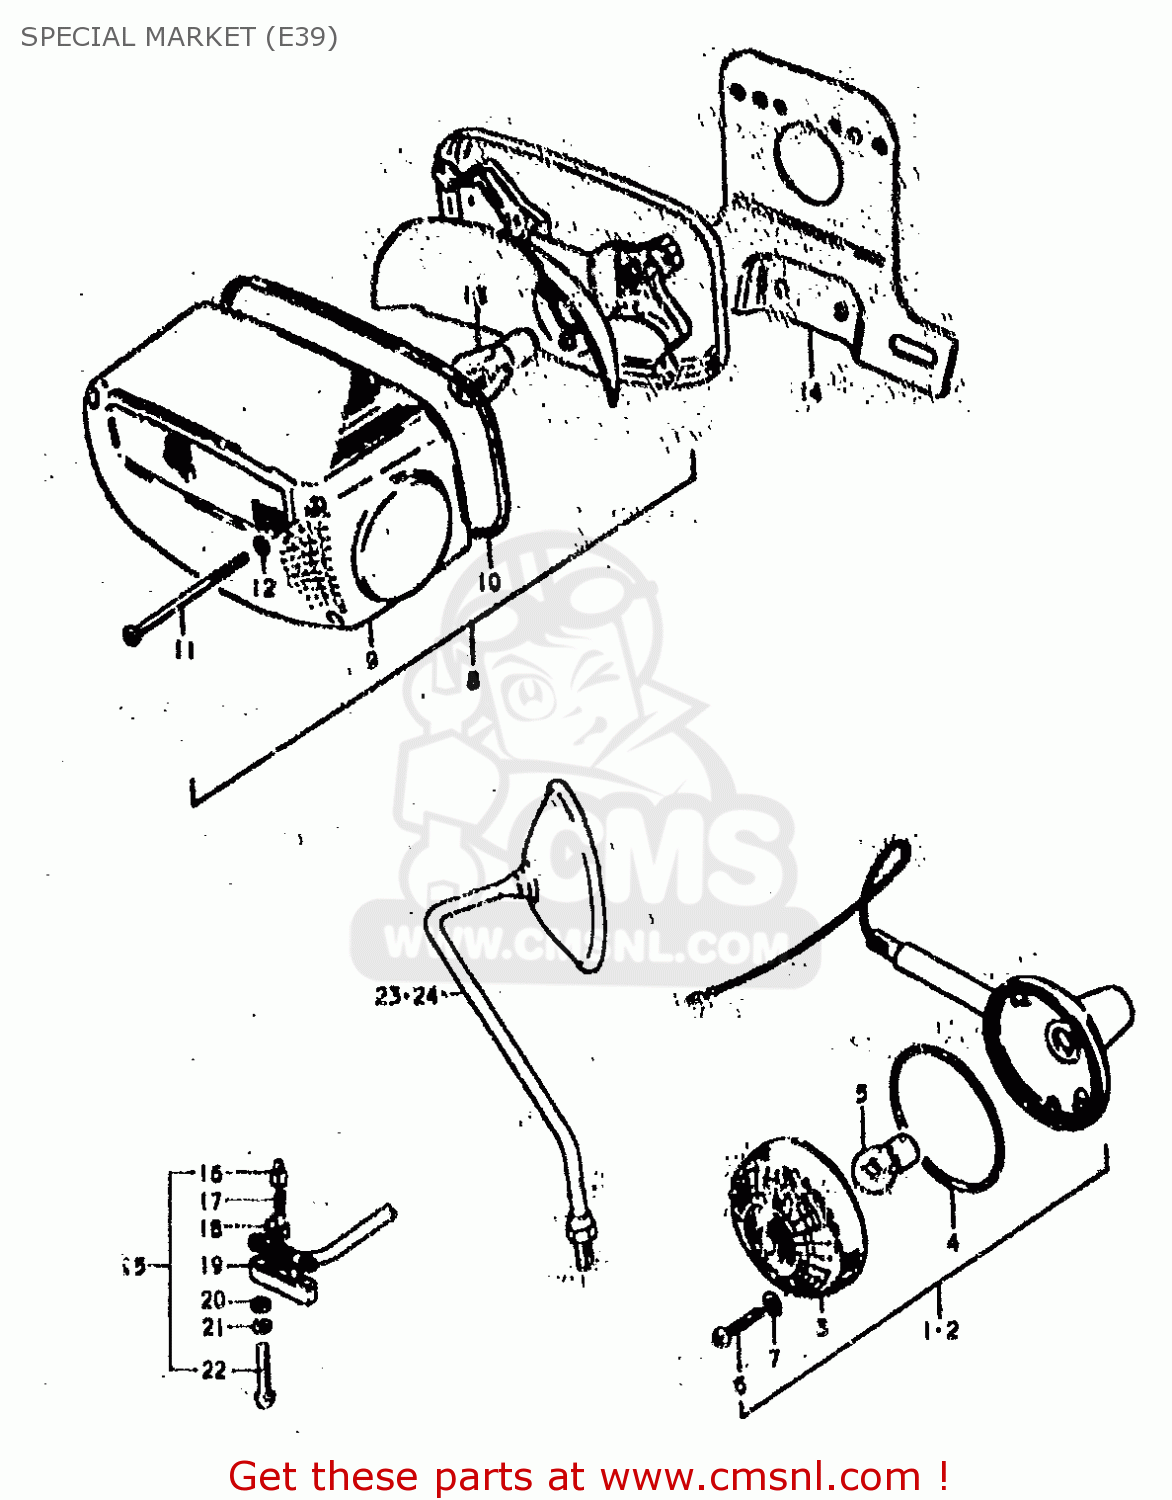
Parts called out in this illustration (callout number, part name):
1	LAMP ASSY,FRONT TURN SIGNAL
2	LAMP ASSY, REAR TURN SIGNAL
3	LENS
4	GASKET (NAS)
5	BULB 12V 21W
6	SCREW
7	GASKET (NAS)
8	LAMP ASSY,REAR COMBINATION
9	LENS,REAR COMBINATION LAMP
10	GASKET (NAS)
11	SCREW (4X55)
12	GASKET (NAS)
13	BULB(12V21/5W)
14	PLATE,LICENCE
15	SWITCH ASSY,STOP
16	HOLDER
17	SPRING
18	PLATE
19	COVER,FR BK TERMINAL BASE
20	WASHER
21	LOCK WASHER
22	SCREW
23	MIRROR ASSEMBLY,RIGHT
24	MIRROR ASSEMBLY,LEFT
